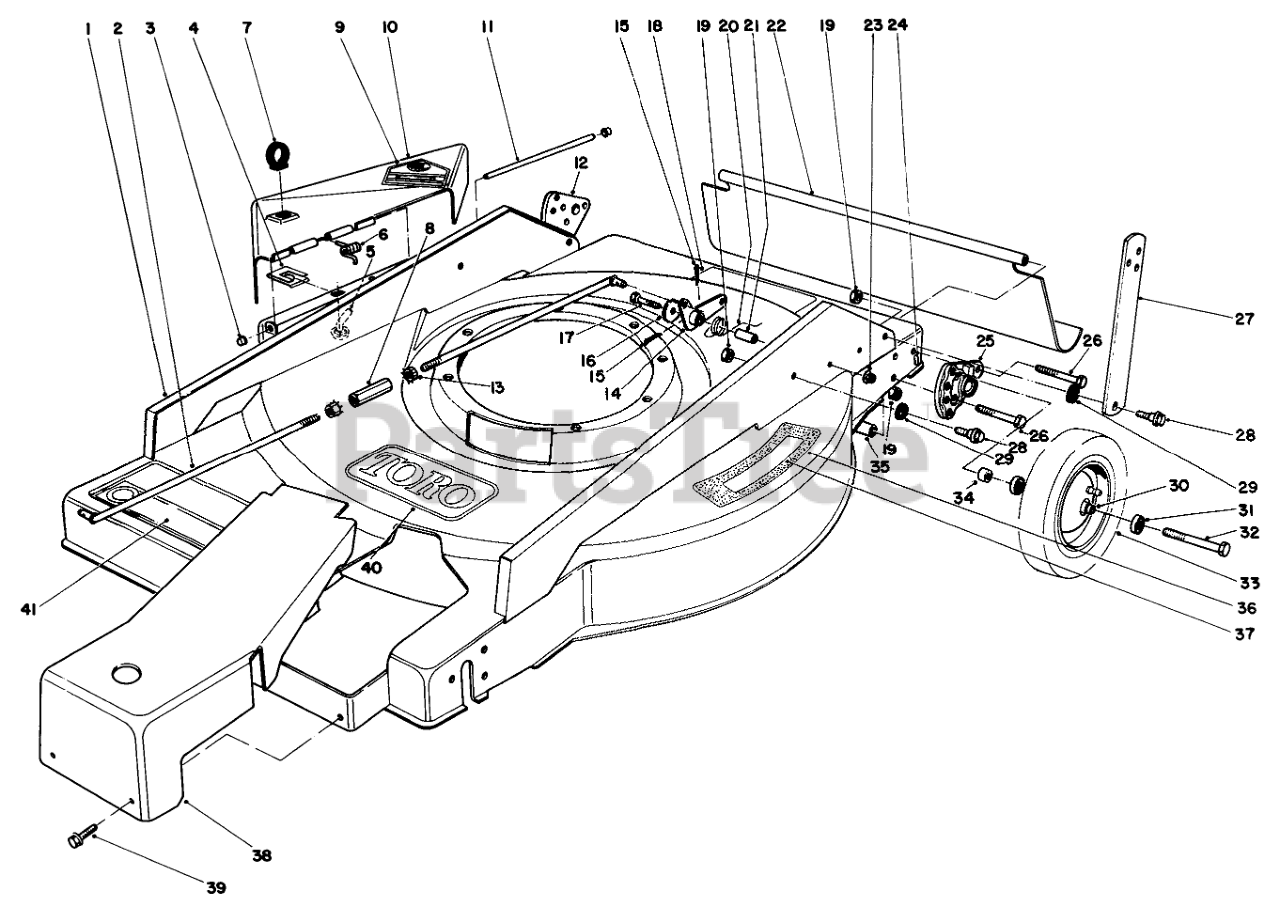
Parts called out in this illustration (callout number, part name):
1	Housing (Incl. Ref. #36, 37 & 41)
2	Link Control Rod
3	PUSHNUT-CAP, WASHER
4	BAG CHUTE CLIP PIN
5	BAG CHUTE PIN
6	TORSION SPRING
7	LIFT LOOP
8	CONTROL ROD SLEEVE
9	DECAL-DANGER
10	Deflector (Incl. Ref. #9)
11	DEFLECTOR PIVOT ROD
12	WHL QUADRANT A-MACH.
13	NUT-KEPS
14	Bell Crank
15	PIN-COTTER
16	WASHER-FLAT
17	SCREW-HH
18	DECAL SAF INST
19	NUT-LOCK, NI
20	TORSION SPRING
21	Spacer
22	REAR SAFETY SHIELD
23	NUT-LOCK, HHF
24	SHIELD ROD
25	WHL QUADRANT B-MACH.
26	SCREW-HH
27	Handle Strap
28	SCREW-SHOULDER
29	HANDLE LATCH SPACER
30	SPACER-BEARING
31	BEARING-WHEEL
32	SCREW-HH
33	Wheel & Tire Assembly (Incl. Ref. #30 & 31)
34	SPACER-WHEEL
35	Rod-Tie
36	PAD STEP
37	Decal Step Pad
38	BELT COVER-MODIFIED
39	SCREW
40	Decal Tow
41	COMMERCIAL DECAL
